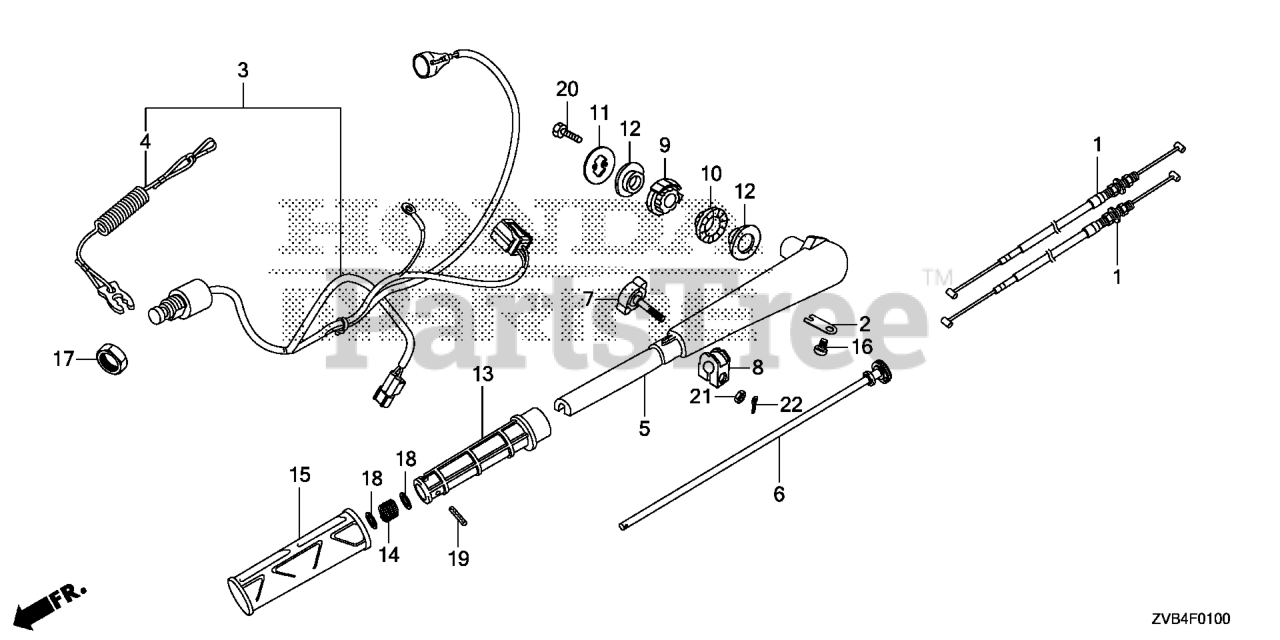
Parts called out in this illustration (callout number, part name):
1	CABLE, THROTTLE
2	PLATE, SHIFT SHAFT
3	SWITCH ASSY., EMERGENCY STOP
4	WIRE, EMERGENCY
5	HANDLEBAR *NHB14M* (COO) (AQUA MARINE SILVER METALLIC)
6	REEL, THROTTLE
7	BOLT, FRICTION
8	BLOCK, THROTTLE FRICTION
9	RUBBER, HANDLE MOUNTING (B)
10	RUBBER, HANDLE MOUNTING (A)
11	PLATE, HANDLEBAR
12	COLLAR, HANDLEBAR
13	PIPE, GRIP
14	SPRING, GRIP PIPE
15	RUBBER, GRIP (COO)
16	SCREW, PAN (6X8)
17	NUT, HEX. (16MM)
18	WASHER, PLAIN (10MM)
19	PIN, SPRING (4X28)
20	BOLT, HEX. (6X16)
21	NUT, HEX. (6MM)
22	PIN, SPLIT 2
